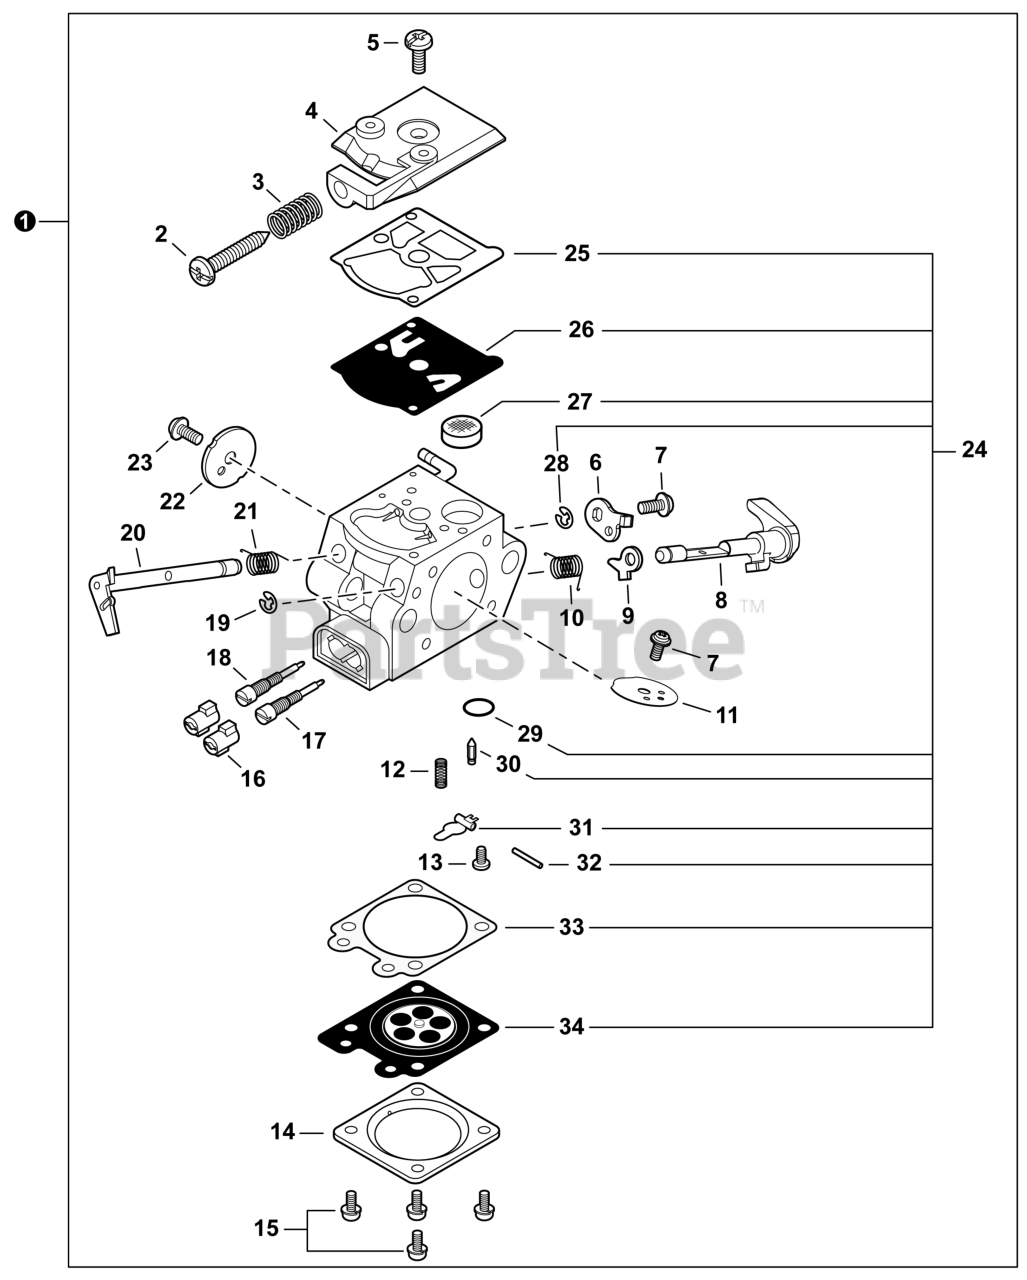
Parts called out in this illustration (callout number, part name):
1	CARBURETOR WT-1243
2	SCREW, IDLE ADJUST
3	SPRING, IDLE ADJUST
4	COVER, FUEL PUMP
6	LEVER, THROTTLE
8	SHAFT ASSY, CHOKE
9	LEVER, FAST IDLE
11	VALVE, CHOKE
12	SPRING, METERING LEVER
14	COVER, METERING DIAPHRAGM
16	CAP, LIMITER
17	NEEDLE, MIXTURE
18	NEEDLE, MIXTURE
20	SHAFT, THROTTLE
21	SPRING, THROTTLE RETURN
22	VALVE, THROTTLE
24	REPAIR KIT
25	GASKET, FUEL PUMP
26	DIAPHRAGM, PUMP
27	SCREEN, FUEL INLET
28	E-RING
29	PLUG, WELCH
30	VALVE, INLET NEEDLE
31	LEVER, METERING
32	PIN, METERING LEVER
33	GASKET, METERING DIAPHRAGM
34	DIAPHRAGM, METERING
